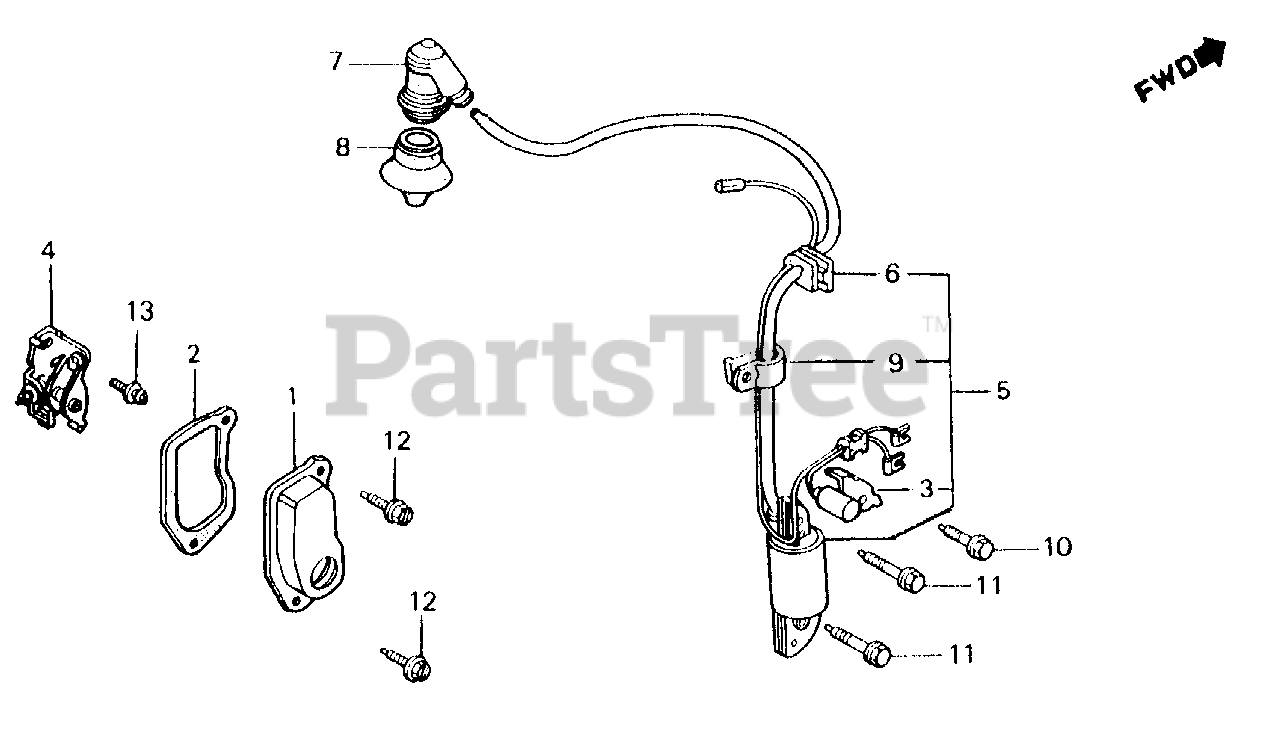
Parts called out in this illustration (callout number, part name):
1	COVER, POINTS
2	GASKET, COVER
4	POINTS ASSY.
5	COIL ASSY., IGNITION (NOT AVAILABLE)
6	GROMMET, WIRE
7	CAP ASSY., NOISE SUPPRESSOR
8	SEAL, IGNITION
9	CLAMP, IGNITION WIRE
10	BOLT, FLANGE (6X12) (CT200)
11	BOLT, FLANGE (6X32)
12	BOLT, FLANGE (5X10)
13	SCREW-WASHER (5X12)
